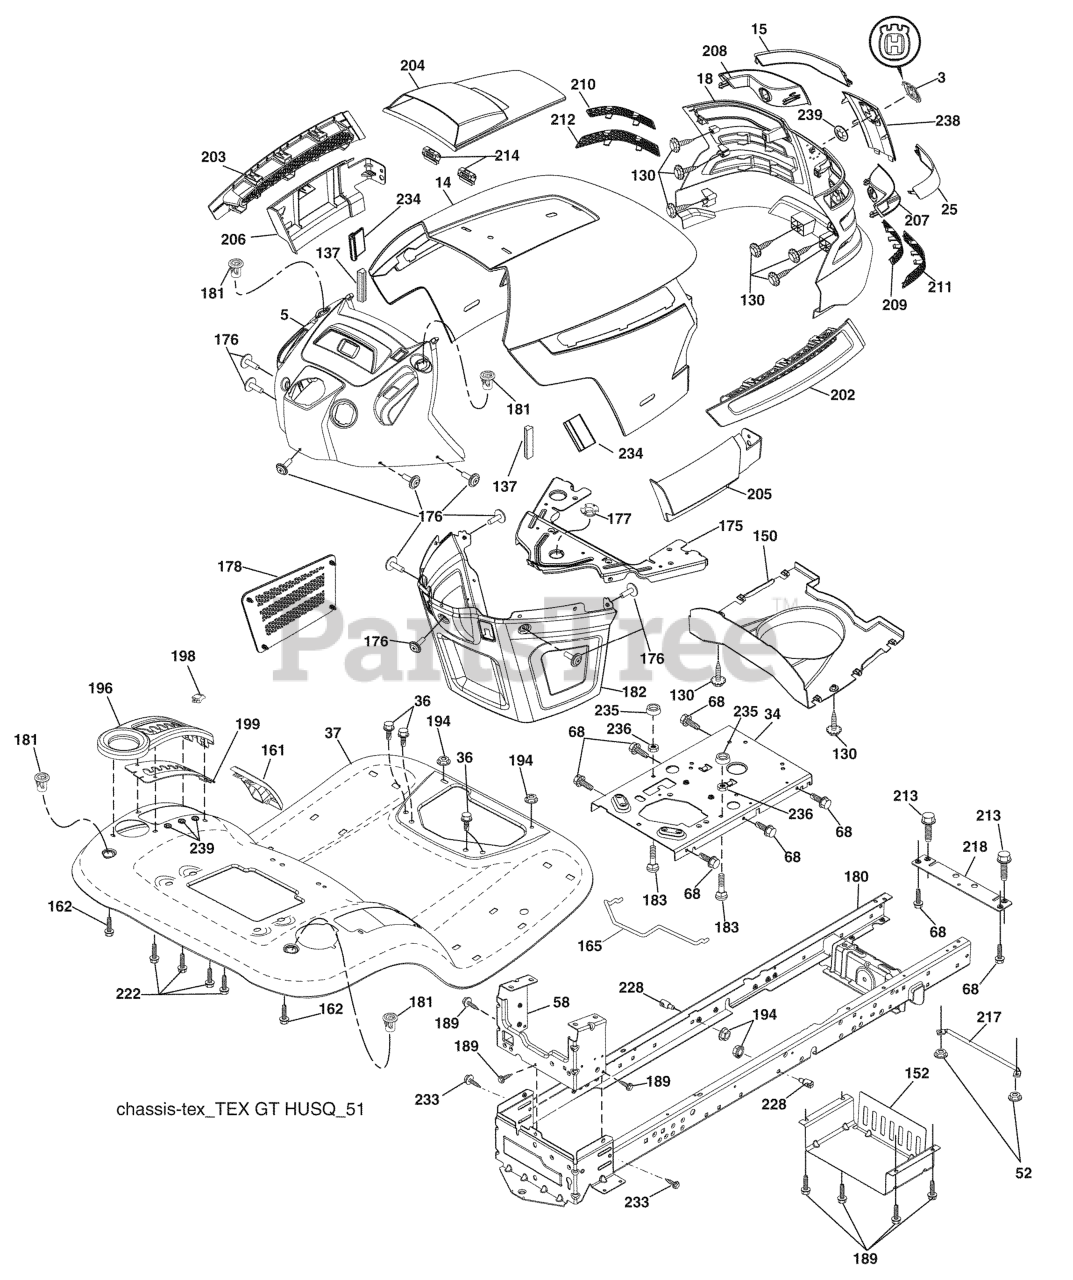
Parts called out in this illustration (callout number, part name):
3	RP LOGO
5	DASH.ASM.HUSQ.GT
14	HOOD
15	LENS.LH.TEX.GT.HUSQ.CL
18	GRILL.ASM.HUSQ.TG/CRD.W/TRIM
25	LENS.RH.TEX.GT.HUSQ.CL
34	PLATE.ENGINE.WELDED.CHASSIS
36	SCREW 5/16"
52	LOCKNUT
58	DRAWBAR.UPPER.2PC,LRG.FENDER
68	Screw Thdrol. 5/16-18 x 1/2
130	SCREW.#10 X 0.750.BOS
137	BUMPER DASH
150	AIR.DUCT.HOOD.TEX.GT.HUSQ
152	SHIELD.BROWNING.W/TEX
161	CONSOLE FUEL WINDOW
162	SCREW.HI-LO.CONSOLE
165	SUPPORT.TANK.REAR.W/TEX
175	PLATE.CROSSMEMBER.HUSQ
176	SCREW.#10-24X5/8.RN.QU
177	BUSHING, STEERING
178	CARGO.ASM.NET.TXGT.W/C
180	CHASS.WLDMNT.TL.12GA/2P.48/54
181	BUSHING.MNT.FEND.CRGO.
182	DASH.LOWER.COMMON.12V.ADAPTOR
183	BOLT.5/16-18X1-1/4 FULL.THREAD
189	SCREW
194	NUT LOCK HEX FLANGE 5/16-18
196	CONSOLE ASM DECK LIFT
198	Indicator Deck Lift
199	PLATE DECK LIFT
202	VENT.SIDE.HOOD.HUSQ.RH.GREY
203	VENT.SIDE.HOOD.HUSQ.LH.GRAY
204	HOOD VENT
205	SKIRT.HOOD.SIDE.HUSQ.RH.GREY
206	SKIRT.HOOD.SIDE.HUSQ.LH.GREY
207	BEZEL.RH.TEX.GT.HUSQ
208	BEZEL.LH.TEX.GT.HUSQ
209	INSERT.HEX.GRILL.HUSQ.GREY
210	INSERT.HEX.GRILL.HUSQ.
211	INSERT.HEX.GRILL.HUSQ.
212	INSERT.HEX.GRILL.HUSQ.
213	BOLT
214	CLIP.RETAINER.TINNER.
217	ROD.PIVOT.HOOD
218	X-PIECE.HOOD.STOP.NON/
222	SCREW.1/4-20X5/8
228	STUD.FASTNER.W/ANTI-ROTATE
233	BOLT.SHOULDER
234	BUMPER.HOOD.TEX.HUSQVARNA
235	SPACER FENDER
236	NUT.CENTERLOCK.5/16-
238	TRIM.HUSQ.TG/CRD.SERVICE
239	NUT PUSH M
